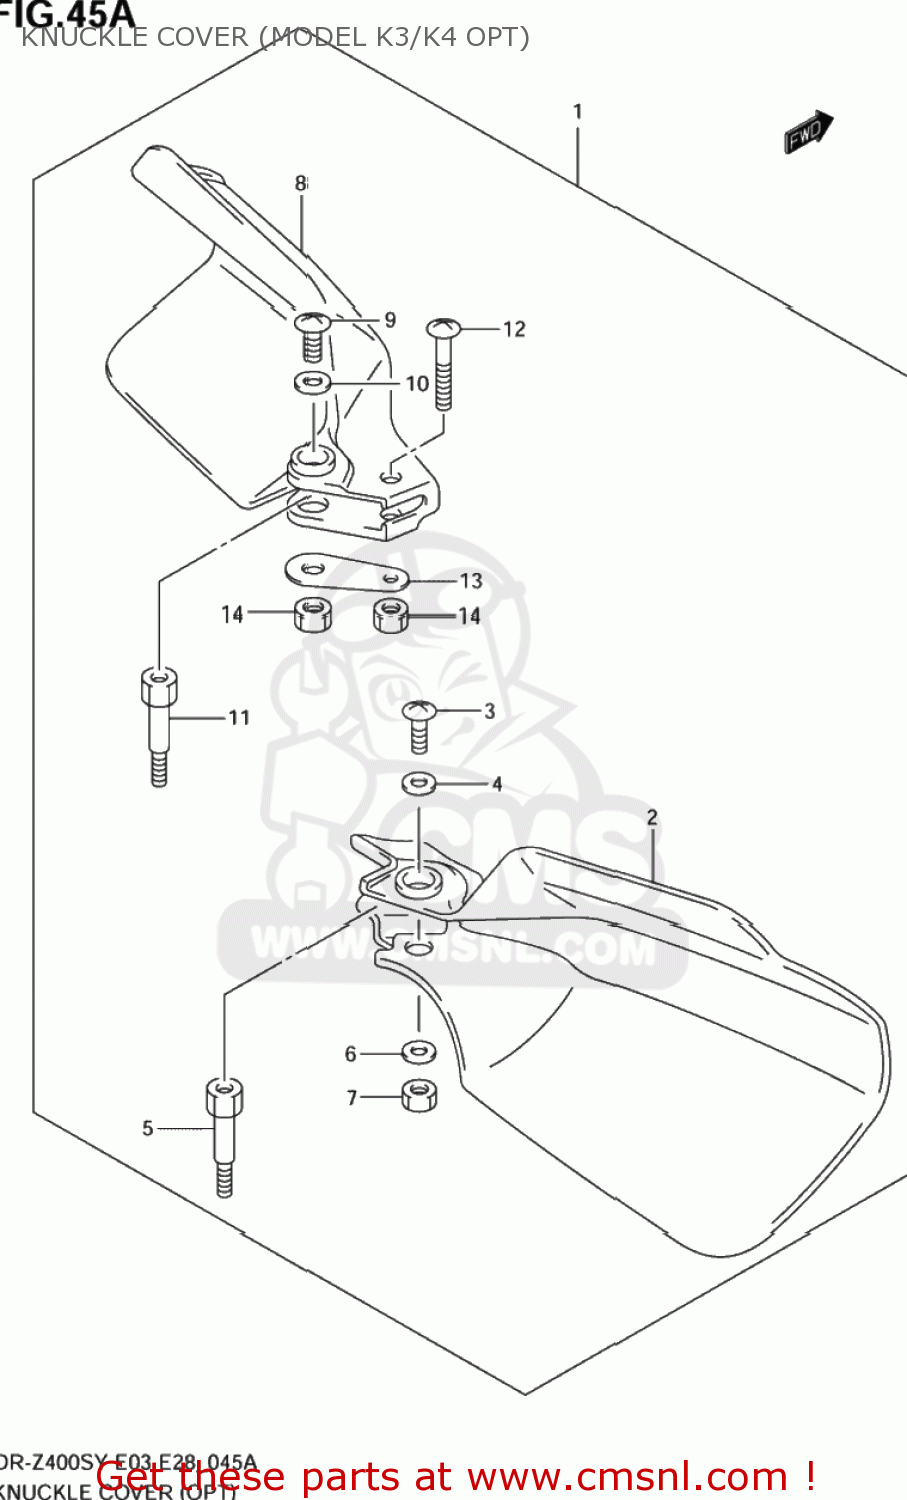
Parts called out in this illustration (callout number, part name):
1	COVER SET,KNUC
2	COVER,KNUCKLE,R
3	SCREW
4	PLATE,KNUCKLE COVER,R UPR
5	BOLT,BRAKE LEVER PIVOT
6	WASHER(6.5X16X1.6)
7	NUT 6MM
8	COVER,KNUCKLE,L
9	SCREW
10	WASHER(5.5X16X1.2)
11	BOLT,LEVER PIVOT
12	SCREW(6X35)
13	PLATE,KNUCKLE COVER,L LWR
14	NUT 6MM
